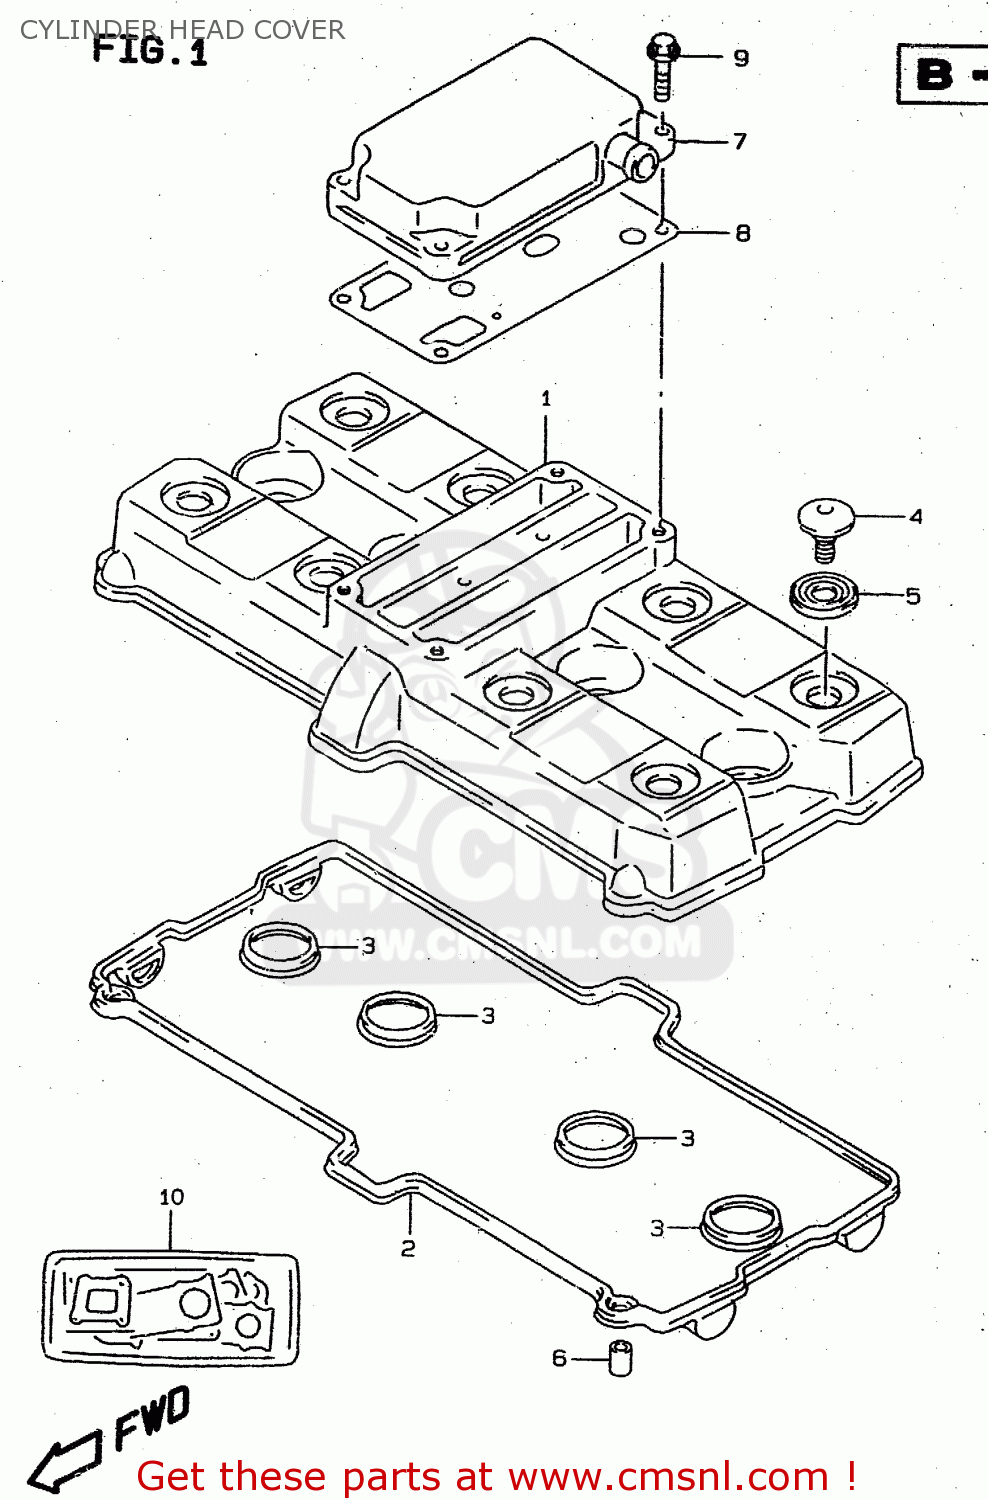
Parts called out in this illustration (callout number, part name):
1	COVER,CYLINDER HEAD
2	GASKET,CYL HEAD COVER NO.1
3	GASKET,CYL HEAD COVER NO.2
4	BOLT(7X17.5)
5	WASHER(10.6X25.5X2.3)
6	PIN(6.2X8X11)
7	COVER,BREATHER
8	GASKET,BREATHER COVER
9	BOLT
10	GASKET SET (NAS)
